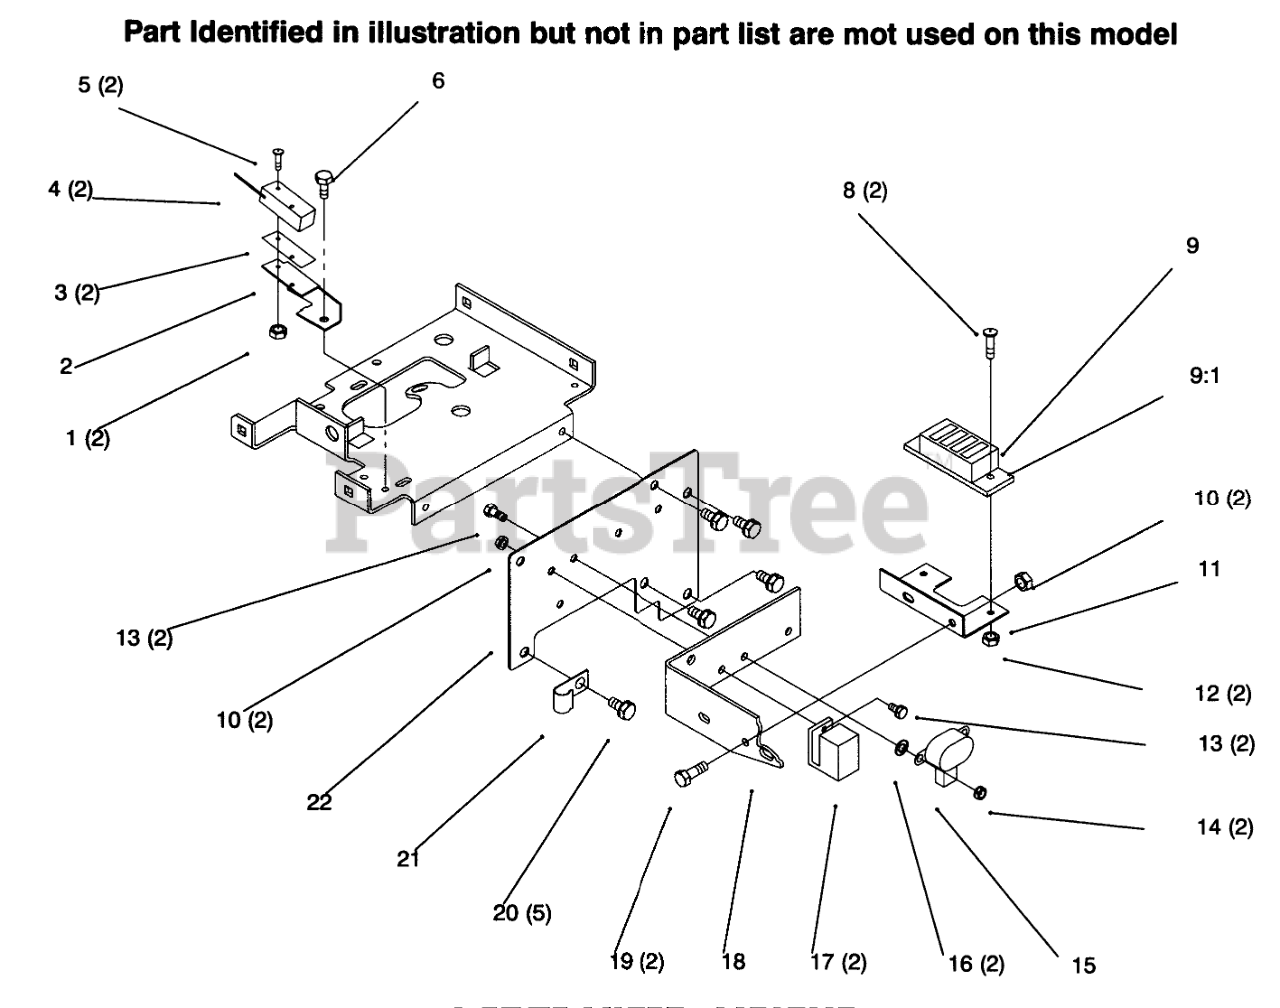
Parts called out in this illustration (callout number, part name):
1	NUT-HEX
2	BRACKET-SWITCH
3	BARRIER - SWITCH
4	SWITCH
5	SCREW-PHL 4-40X1 1/4
6	SCREW-HWH
8	SCREW-PAN
9	WIRING-HARNESS & DIA
9:1	FUSE-HOLDER 4 WAY
10	NUT-LOCK, NI
11	FUSE HOLDERB
12	Nut
13	SCREW1/4-20X5/8 WHIZ
14	NUT-HEX
15	Solenoid
16	WASHER-LOCK/EXT
17	RELAY
18	BRACKET-BELTB
19	SCREW-HH
20	Bolt
21	CLIP
22	Front Plate
23	ASSY WIRE
